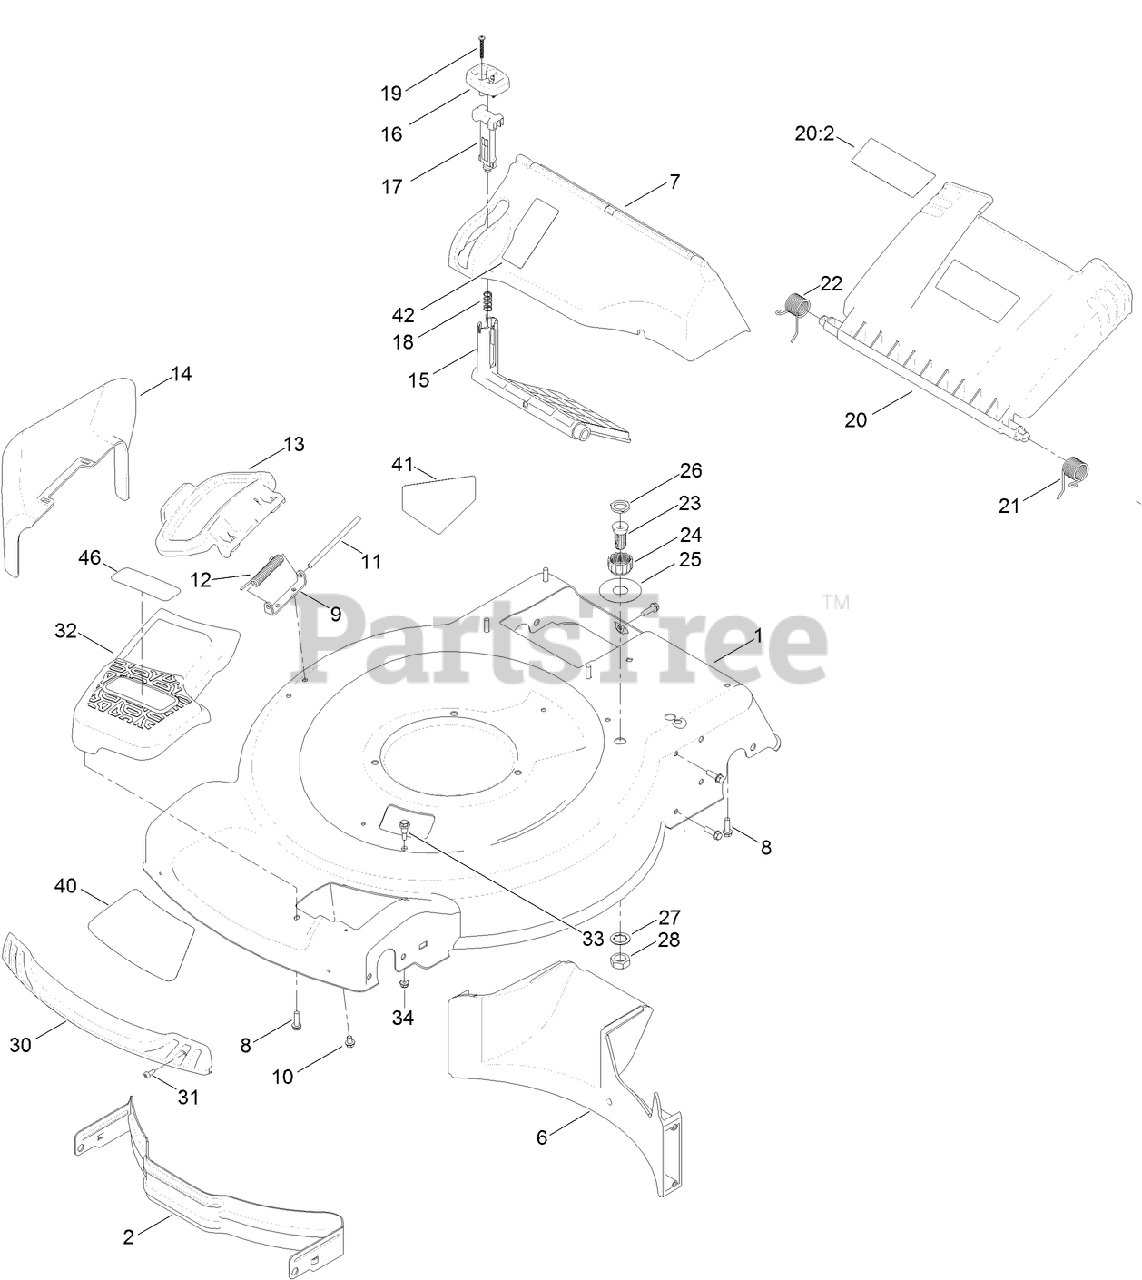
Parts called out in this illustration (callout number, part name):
1	HOUSING ASM
2	BAFFLE-FRONT
6	BAFFLE-REAR
7	CHUTE-RECYCLE
8	SCREW-HWH
9	BRACKET-COVER
10	SCREW-HWH
12	SPRING-TORSION
13	DEFLECTOR-SIDE
14	CHUTE-DISCHARGE, SIDE
15	DEFLECTOR-RECYCLE
16	KNOB-RECYCLE
17	LATCH-RECYCLE
18	SPRING-COMPRESSION
19	SCREW-PPH
20:2	DECAL-WARNING
21	SPRING-TORSION
22	SPRING-TORSION
23	PORT-WASHOUT
24	COUPLING-HOSE, WASHOUT PORT
25	DECAL-PORT, WASHOUT
26	WASHER-SEAL, WASHOUT PORT
27	WASHER-LOCK
28	NUT-JAM
30	BUMPER
31	SCREW-FORMING, THREAD
32	COVER-BELT, FRONT
33	BOLT-SHOULDER
34	NUT-LOCK, NI
40	DECAL-DECK
41	DECAL-DANGER
46	DECAL-COVER
